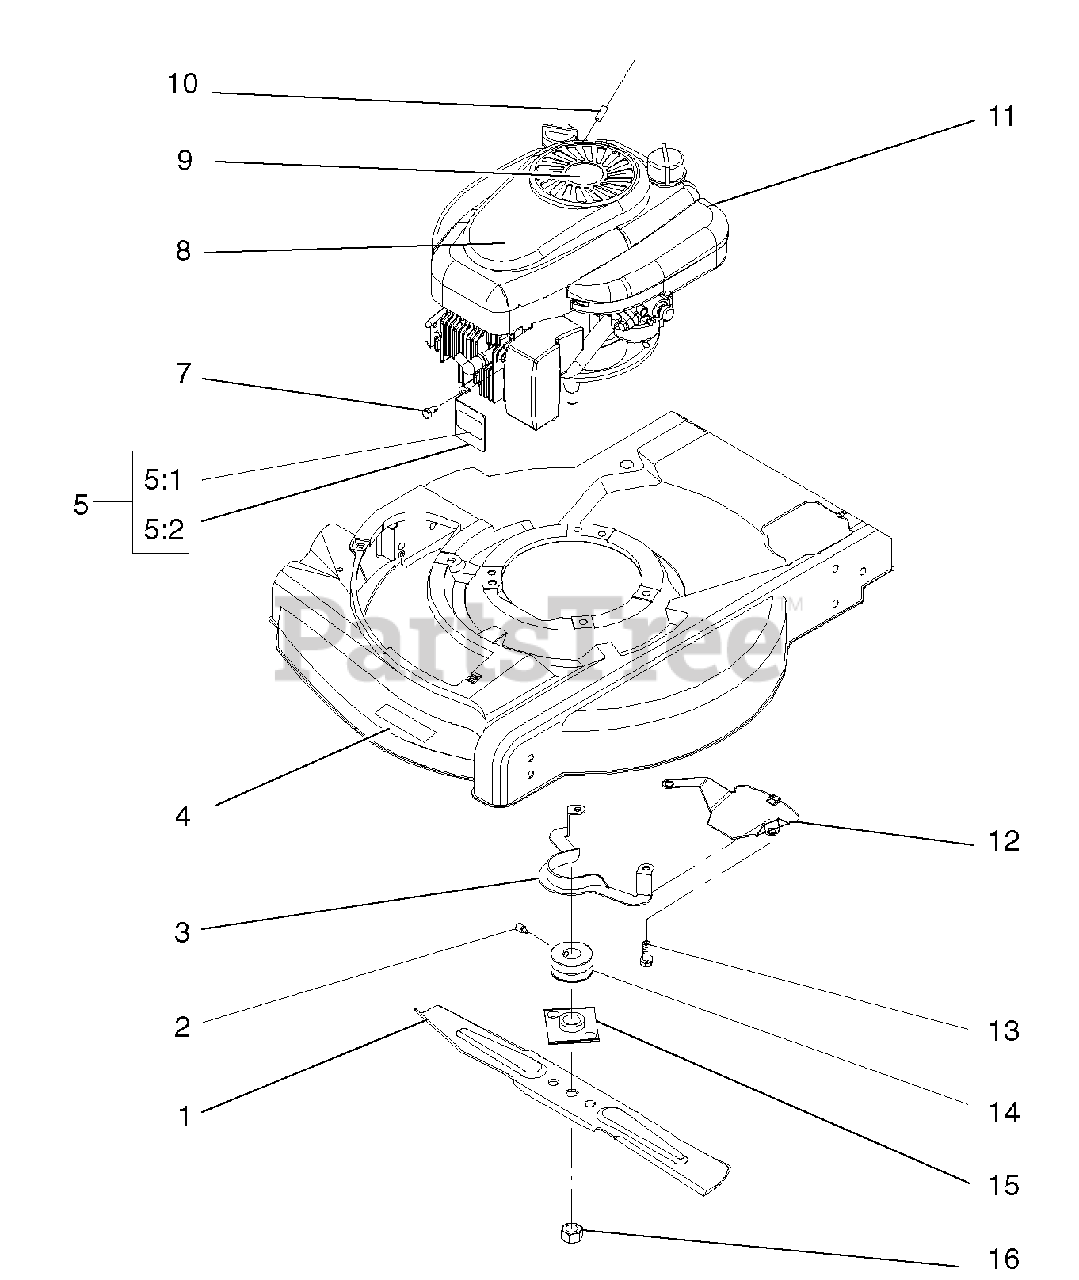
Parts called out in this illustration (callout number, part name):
2	Screw-Set,Cone Point
3	Guide-Belt
5	ASM-Muffler Guard
5:1	Decal-Surface, Hot
5:2	Guard-Muffler
8	Applique
9	Decal-Recoil
10	Stop-Rope
11	Engine-Lev115 Es,Zs
12	Shield-Grass
13	Screw-Taptite W/Patch
15	Blade Retainer ASM
16	Nut-Blade
